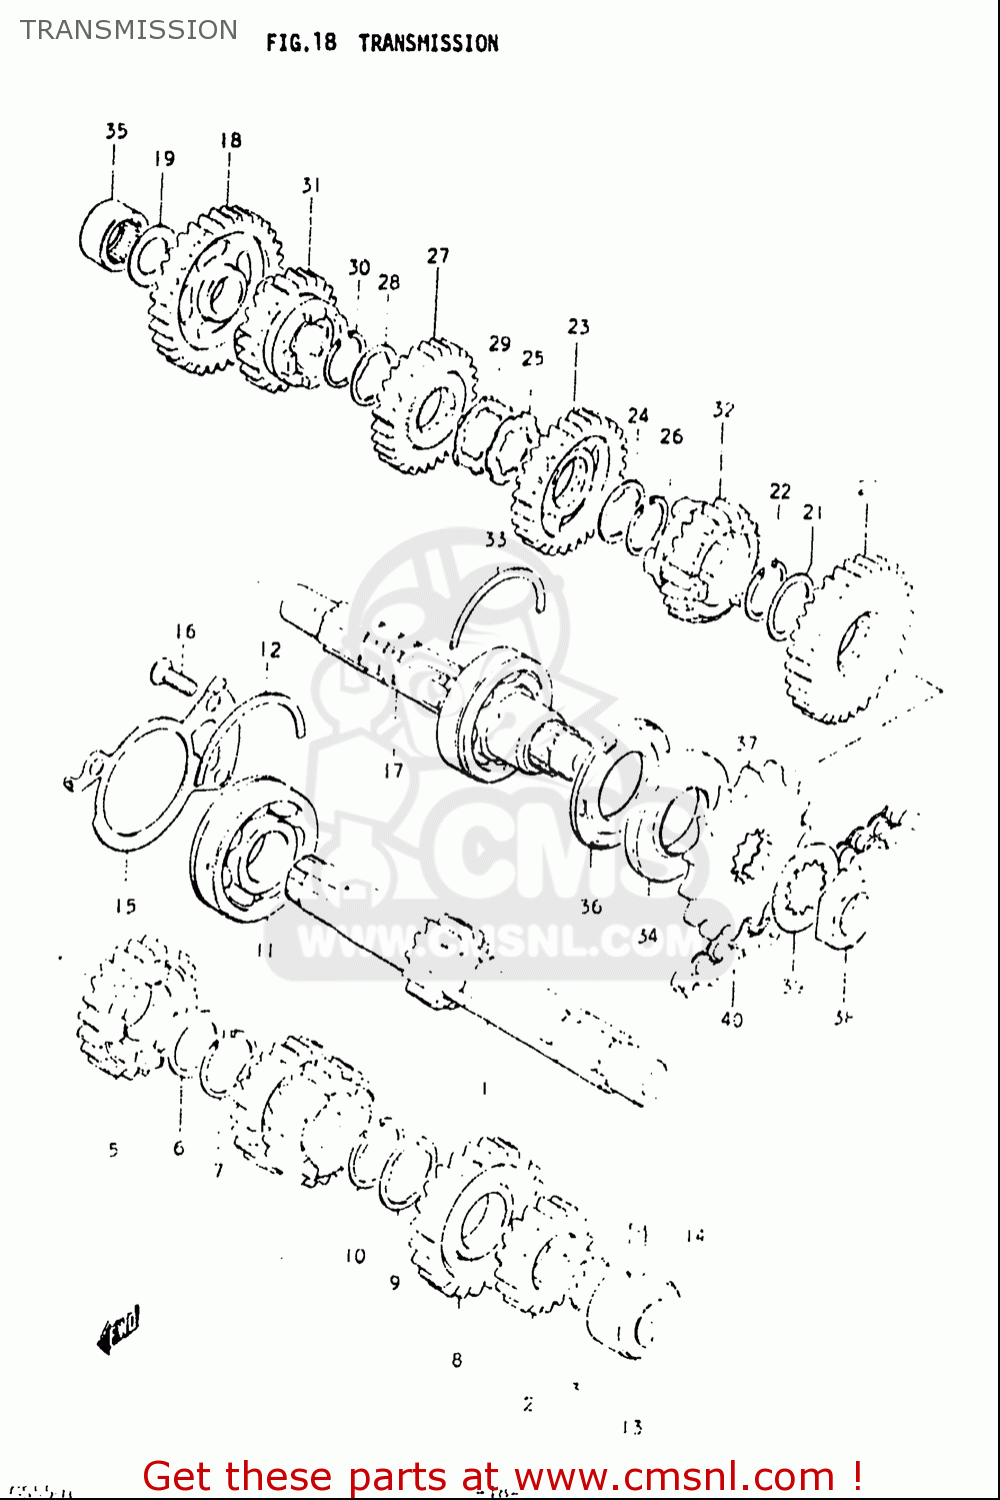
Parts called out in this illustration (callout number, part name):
1	SHAFT,COUNTER
3	RING,SNAP
4	GEAR,THIRD DRIVE
6	SHIM(25X34X1)
7	CIRCLIP
9	WASHER,LOCK
10	CIRCLIP
11	BEARING(25X62X17)
12	C RING
14	PIN
16	SCREW
17	SHAFT,DRIVE
19	WASHER
20	GEAR,SECOND DRIVEN
21	WASHER
22	CIRCLIP
23	GEAR,THIRD DRIVEN
24	WASHER,LOCK
25	WASHER,LOCK
26	CIRCLIP
27	GEAR,FOURTH DRIVEN
28	WASHER,LOCK
29	WASHER
30	CIRCLIP
31	GEAR,FIFTH DRIVEN
32	GEAR,SIXTH DRIVEN
33	C RING
34	SEAL,OIL(32X62X7)
35	BEARING(20X34X17)
36	SEAL,OIL(32X62X5.5)
37	SPROCKET,ENGINE(15T)
38	NUT
39	WASHER,LOCK
